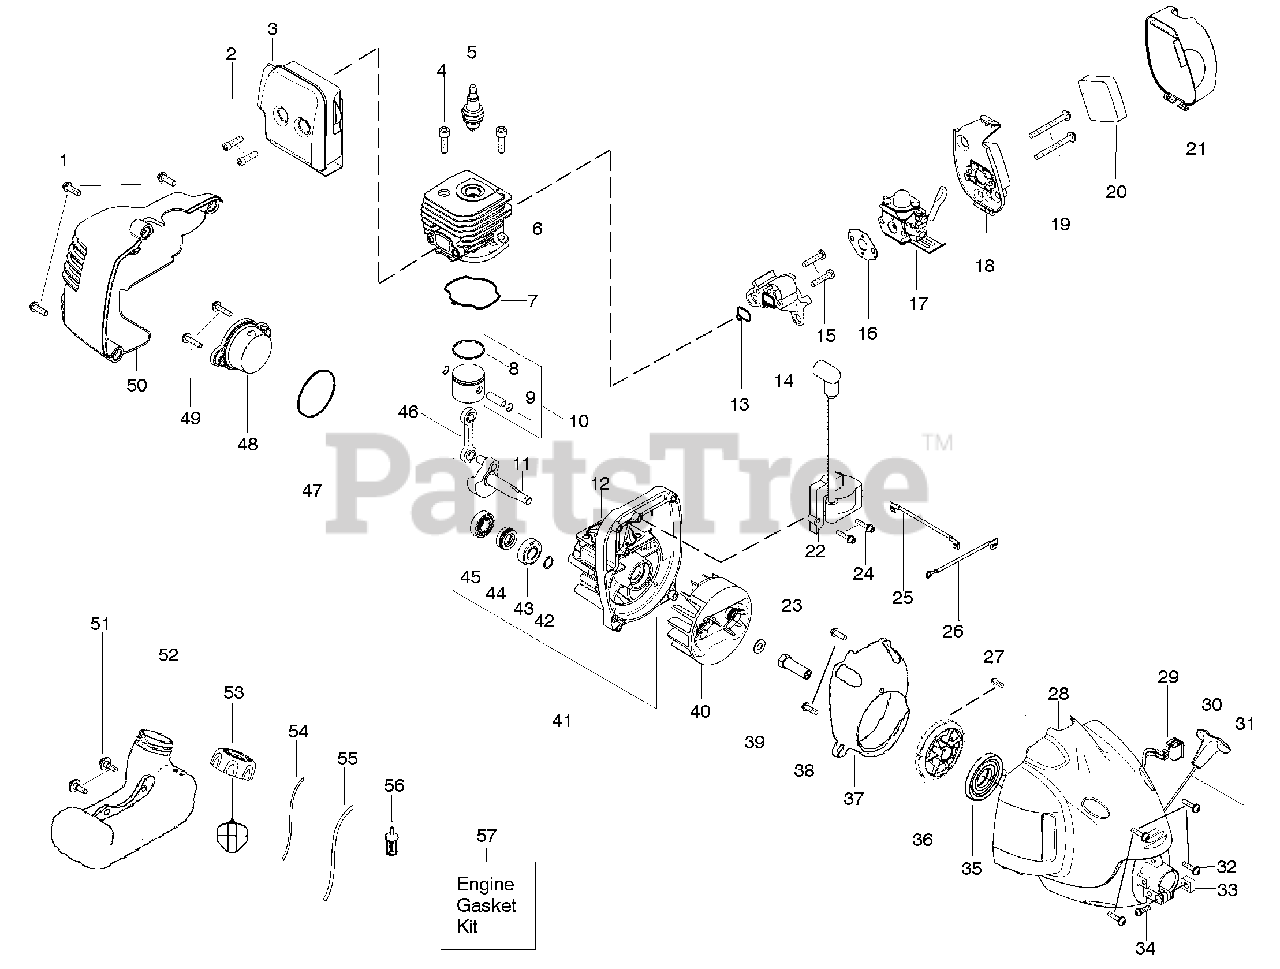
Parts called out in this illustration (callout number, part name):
2	Bolt-Muffler
3	Assy-Muffler/Shield
4	Screw-Cylinder
5	Spark Plug (RCJ 6Y)
6	Cylinder
7	Seal-Cylinder (kit)
8	Piston Ring
9	Retainer-Piston Pin
10	Kit - Piston
11	Assy-Crankshaft
12	Assy-Crankcase
13	Seal-Cyl/Carb.(kit)
14	Adapter-Carb.
16	Gasket-Carb. (kit)
17	Kit-Carb. Zama (C1U-W18)
17	Kit-Carb. Walbro (WT-669)
20	Foam-Air Filter
21	Cover-Air Box
22	Ignition Module
23	Coupling-Drive
25	Assy-Leadwire
26	Assy-Ground Wire
28	Assy.-Fan Hsg
29	Kit-Switch
30	Handle-Starter
31	Kit - Rope
32	Screw
33	Nut 12-24
34	Screw 12-24
35	Spring-Starter
36	Kit-Starter Pulley
37	Baffle
39	Washer-Flat
40	Assy-Flywheel
41	Assy-C'case & C'shaft
42	Retain. Ring-C'shaft
43	Outer Bearing
44	Seal-C'shaft
45	Inner Bearing
46	Kit-Conn. Rod Assy
47	O-Ring-C'case (kit)
48	Assy-Plug
50	Shroud-Rear
51	Retainer-Tank
52	Assy-Fuel Tank
53	Assy-Fuel Cap
54	Kit-Fuel Line (Small)
55	Kit-Fuel Line (Large)
56	Assy-Fuel Pickup
57	Kit-Engine Gasket
